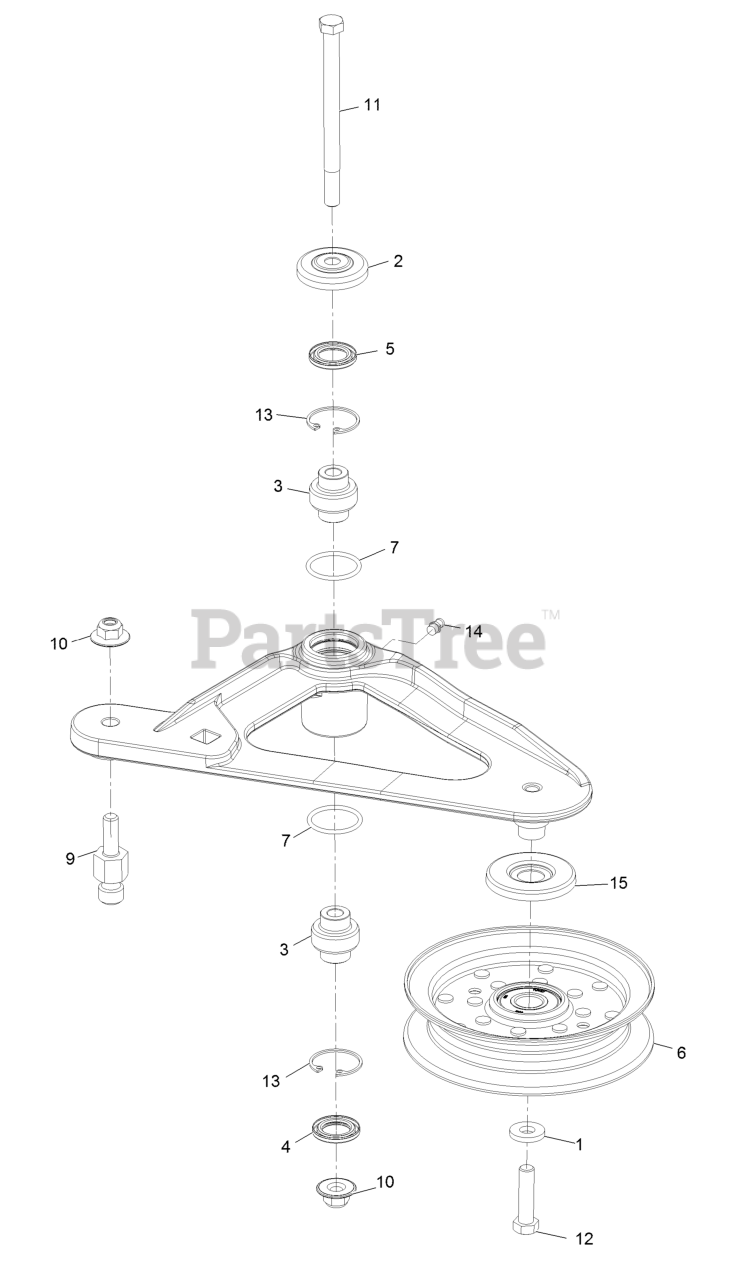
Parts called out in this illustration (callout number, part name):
2	Guard-Top
3	Bearing-Spherical
4	Seal-Lip, Double
5	Seal-Lip, Single
6	Idler-Pulley, Flat
9	Pin-Spring, Anchor
10	Nut-Flange, NI
11	Screw-Shoulder, HH
12	Screw-HH
13	Ring-Snap
14	Fitting-Grease
15	Shield-Guard, Dust
